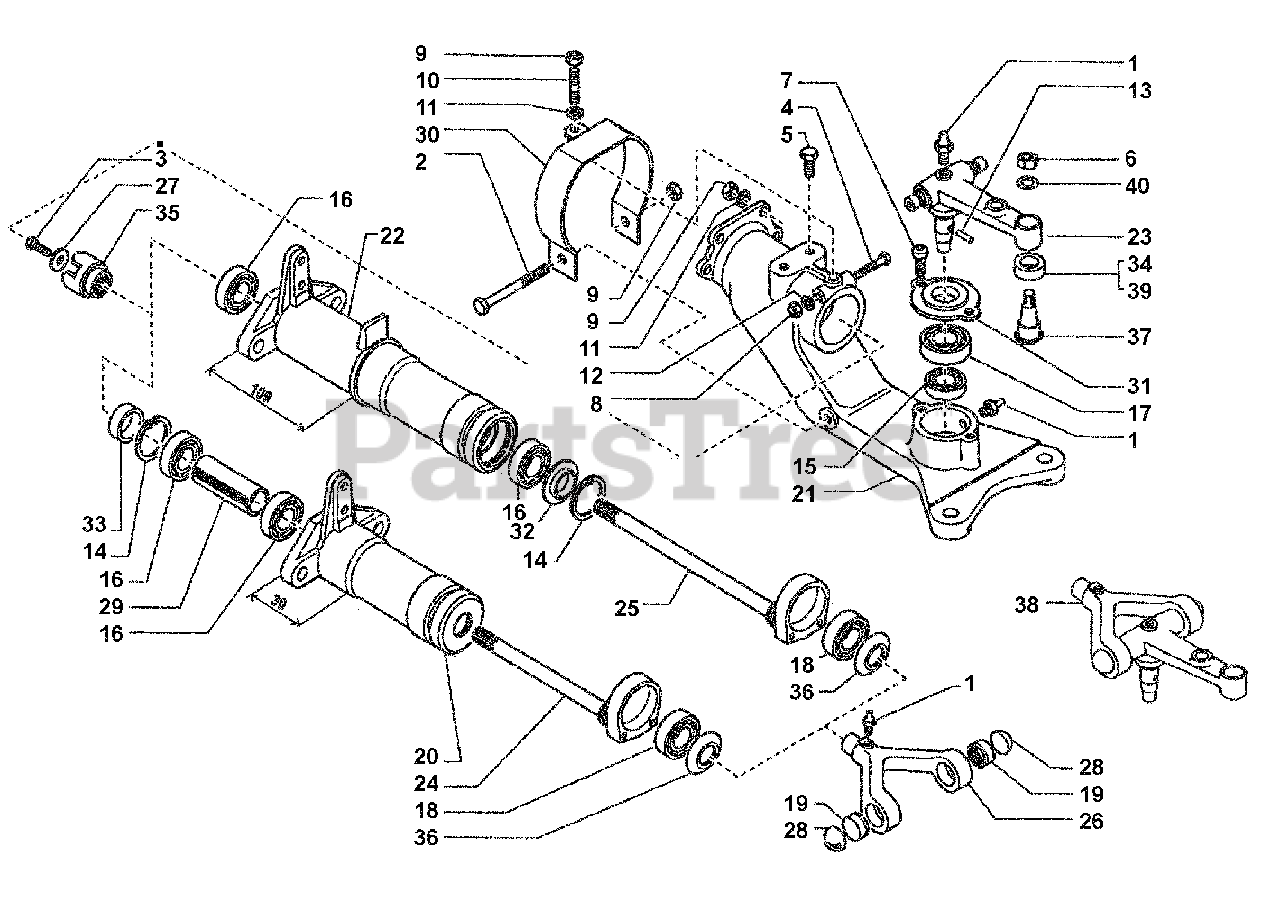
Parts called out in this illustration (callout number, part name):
1	GREASE ZERK M10
2	SCREW, M8X100
3	SCREW, M6X20
4	SCREW, M6X70
5	SCREW, M8X12
6	LOCK NUT DEFORMED
7	SCREW M6X16
8	NUT, SELF LOCKING, M6
9	NUT, SELF LOCKING, M8
10	STUD, M8X26
11	WASHER, FLAT, M8.4
12	WASHER, LOCK, M6.4
13	PIN, LOCKING, M4X35
14	CIRCLIP, INTERNAL
15	BEARING, M15X35X11
16	BEARING M20X47X14
17	BEARING, M25X52X15
18	BEARING, M20X52X15
19	BUSHING PIT
20	BUSHING WITH FLANGE
21	BAR SUPPORT
22	SHAFT HOUSING
23	BLADE CRANK
24	ECCENTRIC SHAFT
25	LONG ECCENTRIC SHAFT
30	ECCENTRIC PROTECTION
31	COVER, BEARING
34	BLADE PIN BUSHING 32MM
35	PTO COUPLER
38	CRANK WITH FORK
39	BLADE PIN BUSHING 37MM
40	WASHER SUPER 37MM
